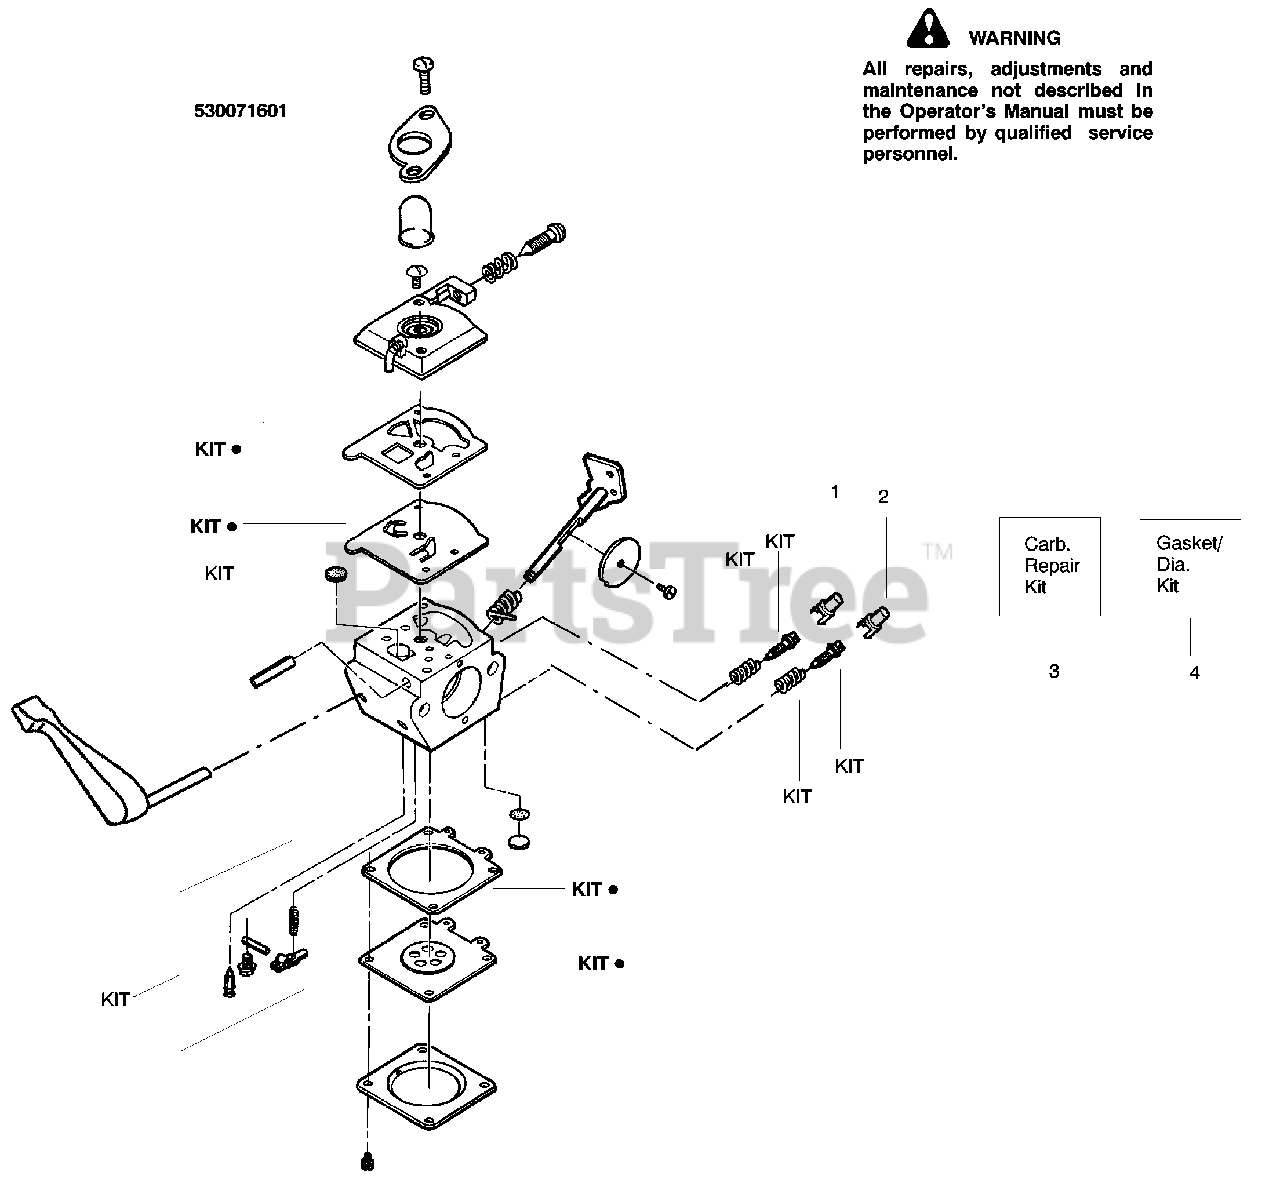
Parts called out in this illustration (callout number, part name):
1	Limiter Cap-Low
2	Limiter Cap-High
3	Carburetor Repair Kit
4	Gasket/Diaphragm Kit
530071601	Carburetor Assembly
